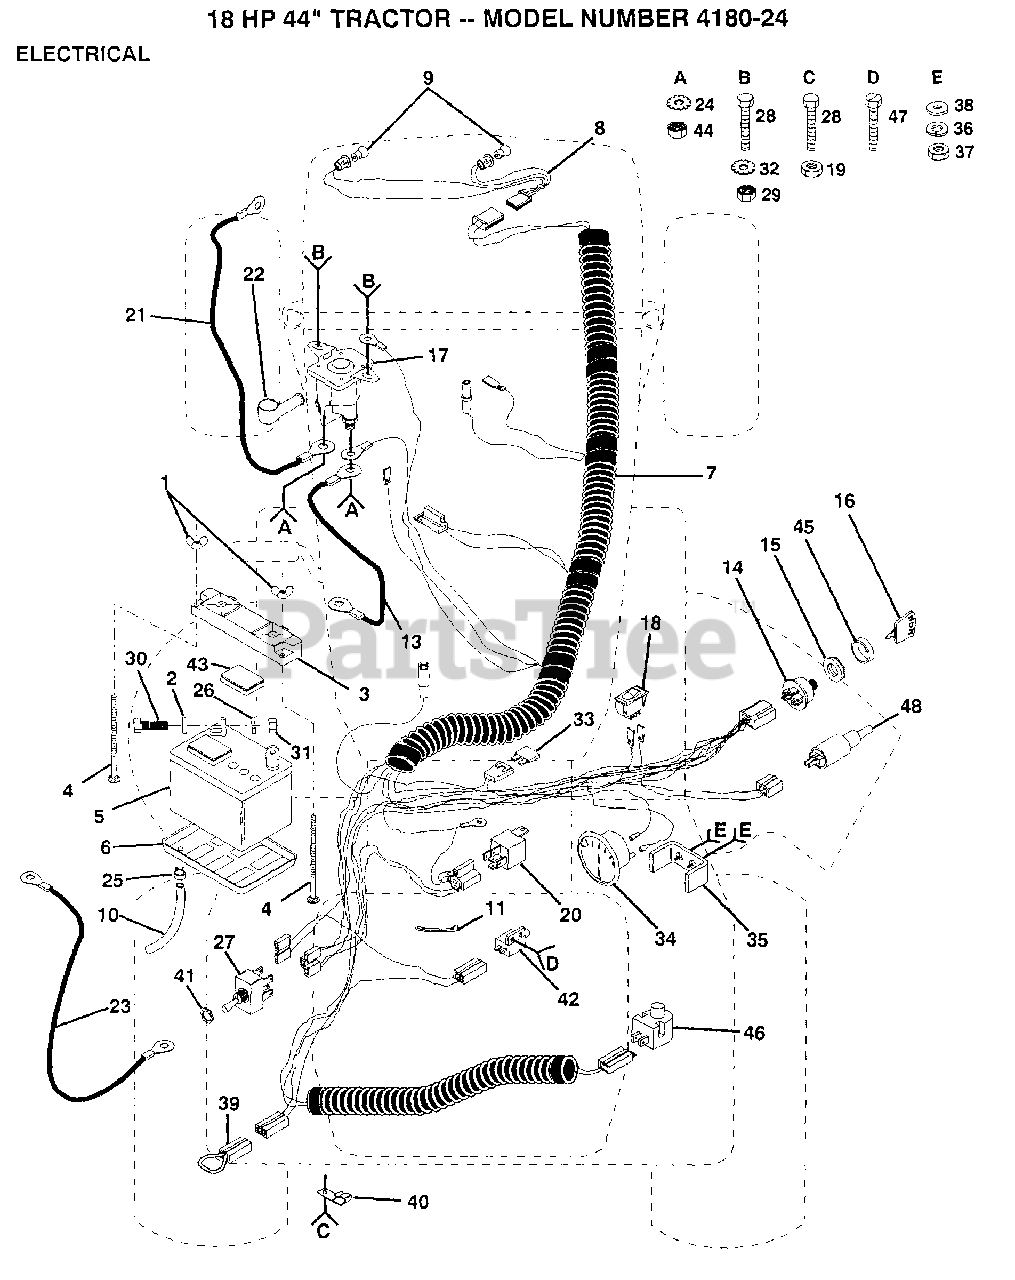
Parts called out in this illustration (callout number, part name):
2	WASHER
4	BOLT
6	"TRAY T, BATTERY"
7	IGNITION HARNESS
11	WIRE TIE
13	CABLE-BATTERY T
15	NUT IGNITION
16	KEY
18	SWITCH LT
20	RELAY ASSY T
21	"CABLE T, BATTERY"
23	CABLE T
25	HOSE CLAMP T
26	LOCKWASHER
28	BOLT
29	NUT
30	BOLT LT
33	FUSE HYT
34	AMMETER T
38	WASHER
40	CLIPT
41	HEX NUT T
42	SWITCH-INTER. GT
43	"CAP,BATTERY "
44	NUT
46	SWITCH SEAT
47	SCREW
